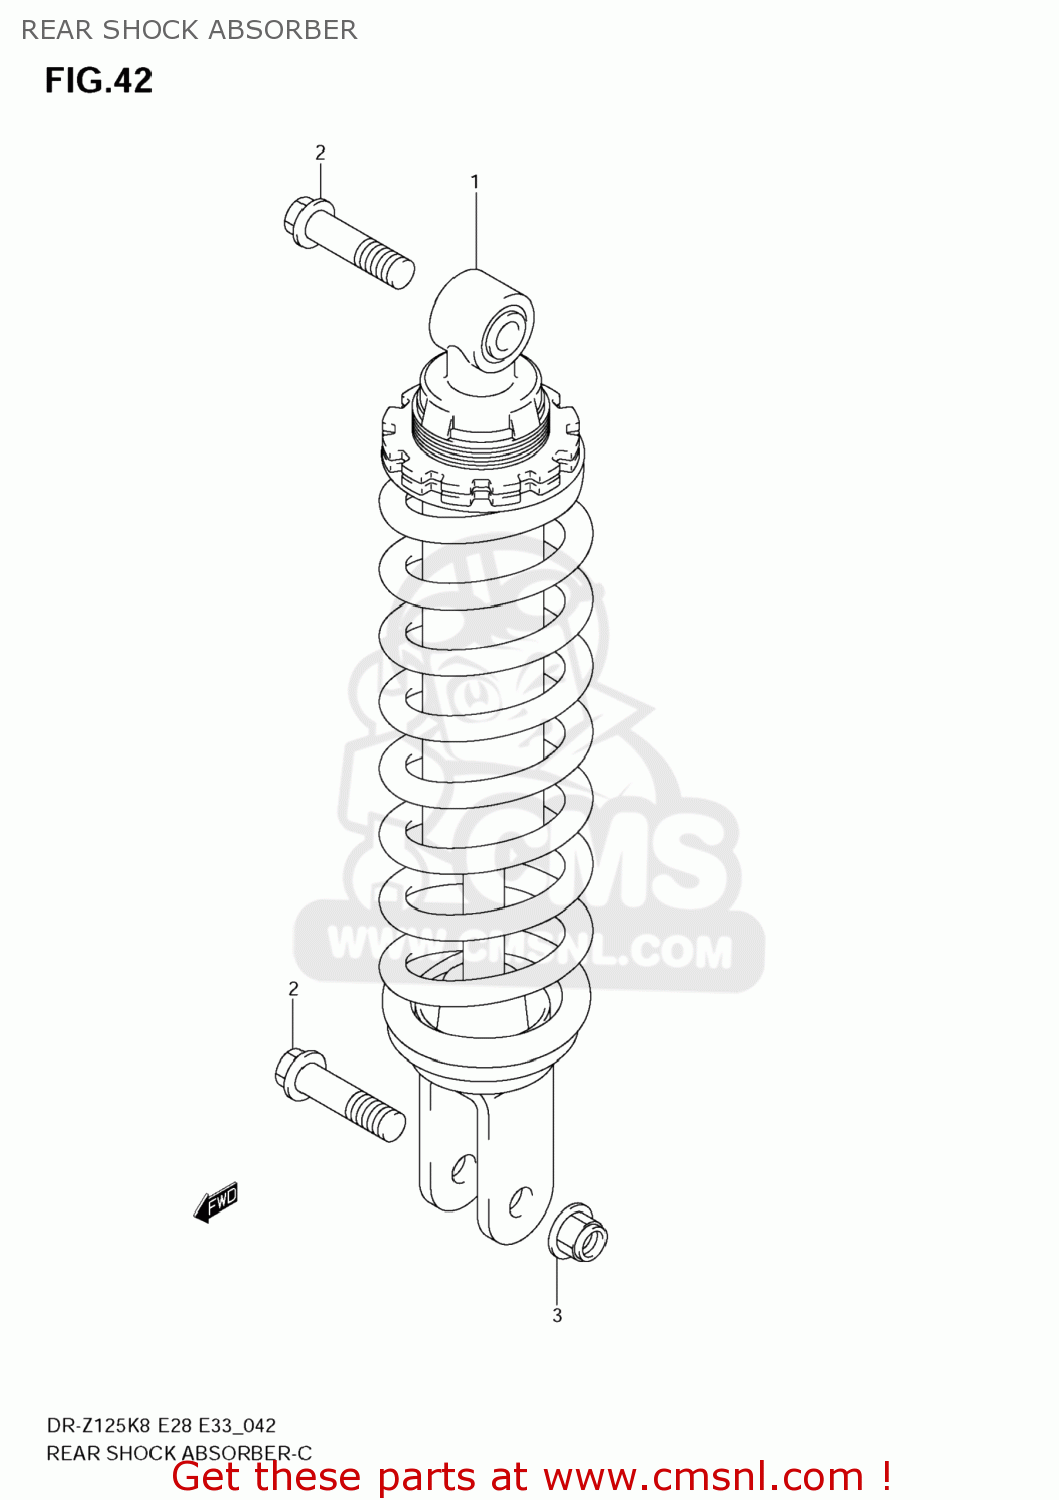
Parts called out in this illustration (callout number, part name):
1	ABSORBER ASSY,RR SHOCK
2	BOLT,RR CUSHION ROD LWR
3	NUT
